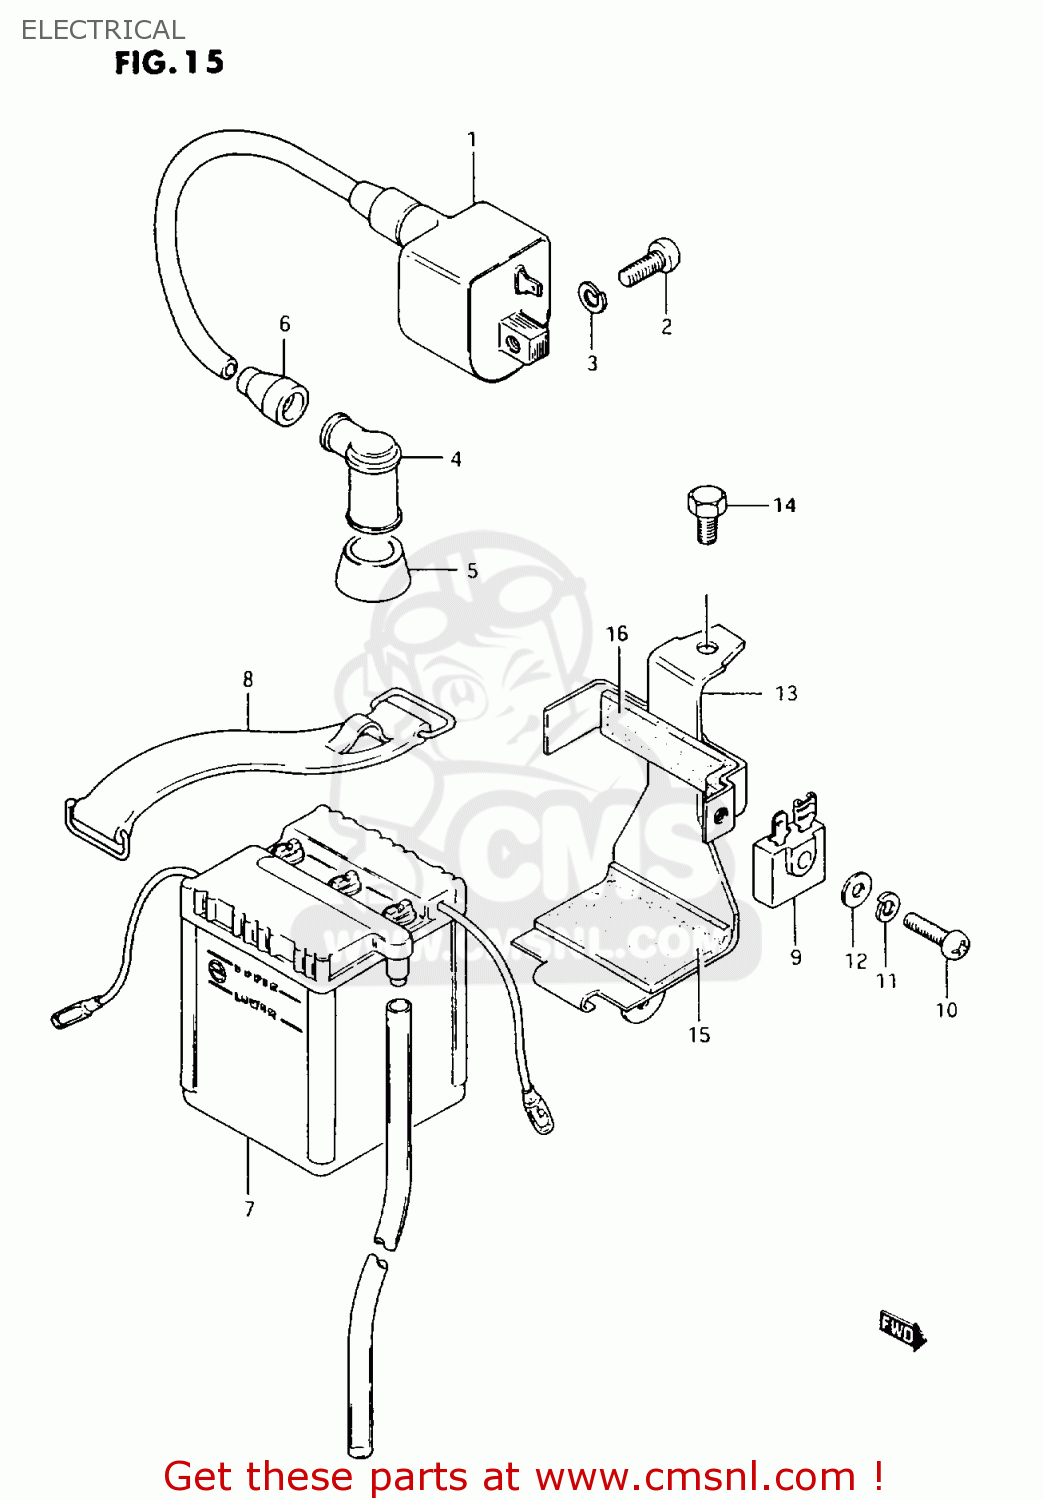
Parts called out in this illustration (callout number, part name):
1	UNIT & COIL ASSY,IGNITION
2	SCREW, 6X20
3	WASHER,LOCK
4	CAP ASSY,SPARK PLUG
5	SEAL,SPARK PLUG
6	SEAL,HIGH TENSION CORD
7	BATTERY ASSY(6N4-2A4.2AH)
8	BAND,BATTERY
9	RECTIFIER ASSY
10	SCREW
11	WASHER,LOCK
12	WASHER
13	HOLDER,BATTERY
14	BOLT
15	PROTECTOR(170X95X3.0)
16	PROTECTOR(170X95X3.0)
